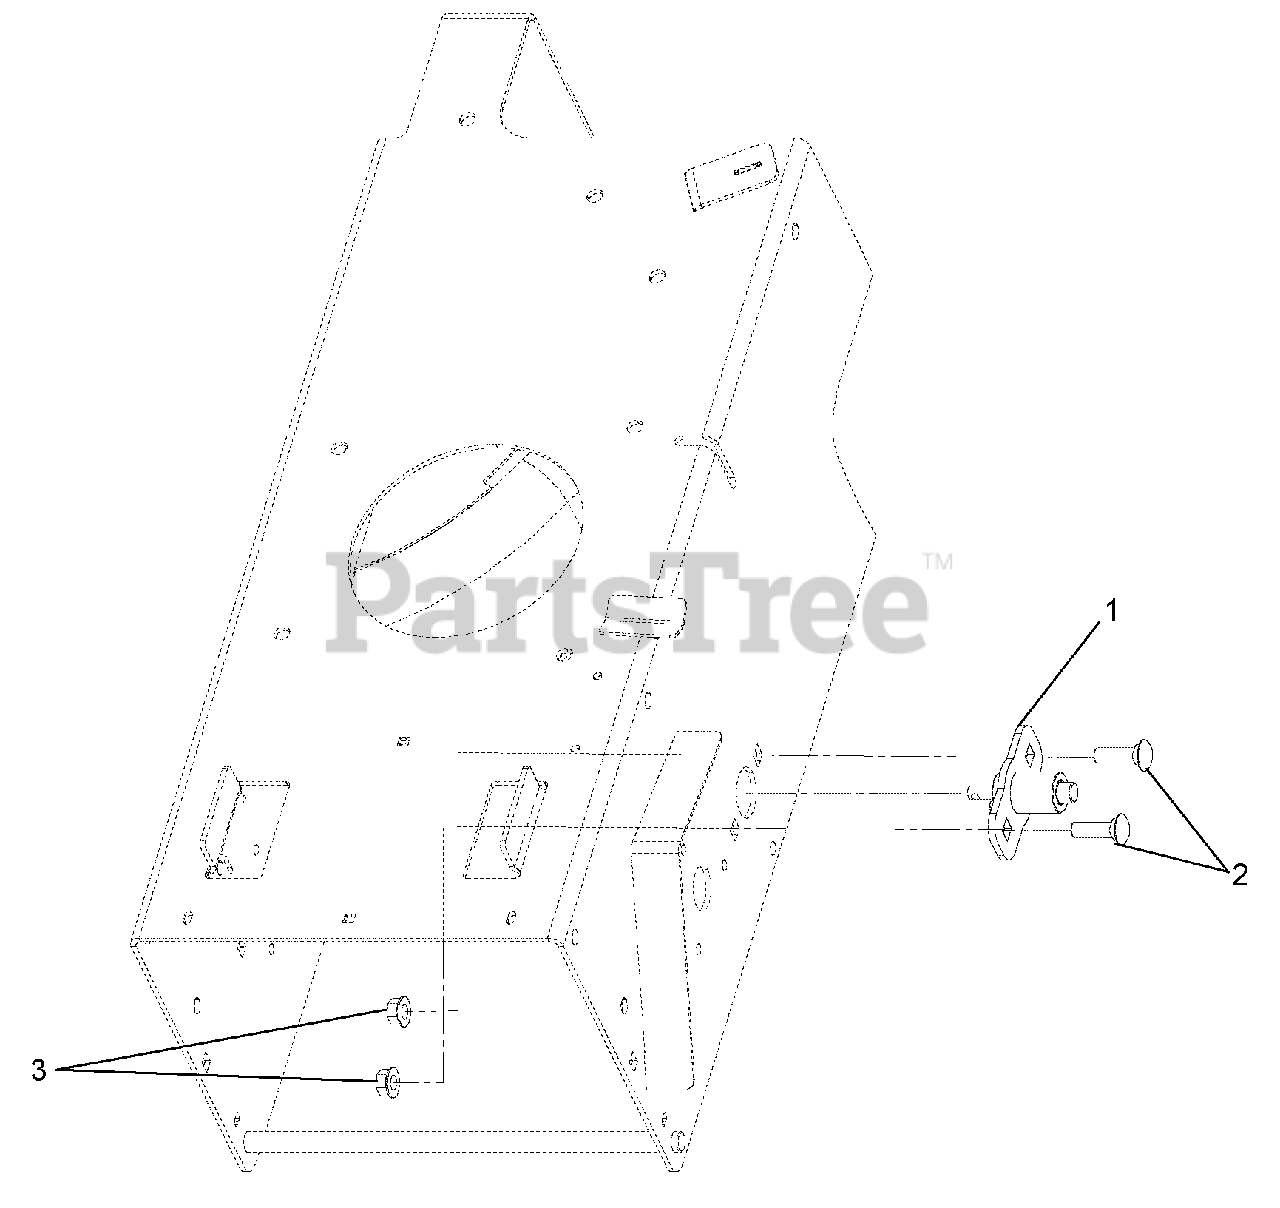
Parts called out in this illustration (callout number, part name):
1	Kit, Pin Brake
2	Bolt, Round Head Square Neck .38-16 x 1.25 Grade 5
3	Nut, Flange .375-16
